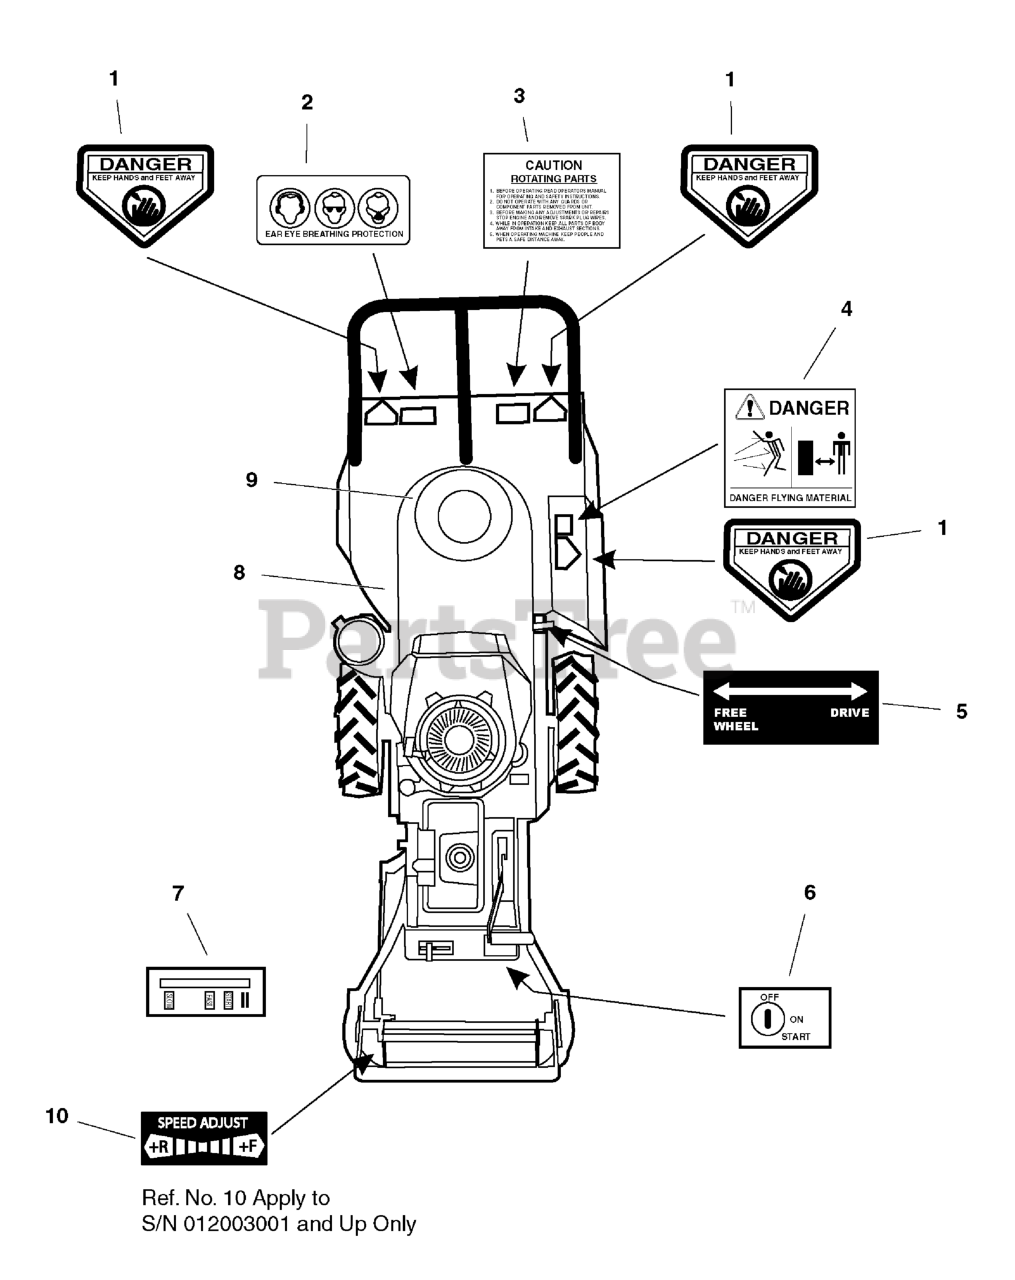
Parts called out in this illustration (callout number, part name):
1	Decal, Danger
2	Decal, Ear Eye Protection Req.
3	Decal, Rotating Parts
4	Decal, Thrown Objects
5	Decal, Transmission Drive
6	Decal, Key Switch
7	Decal, Throttle Control
8	Decal, Pin Stripe
9	DECAL, Simplicity Logo
9	Decal, Ferris Logo
9	Decal, Giant-Vac Logo
9	Decal, Snapper
10	Decal, Speed Adjust
